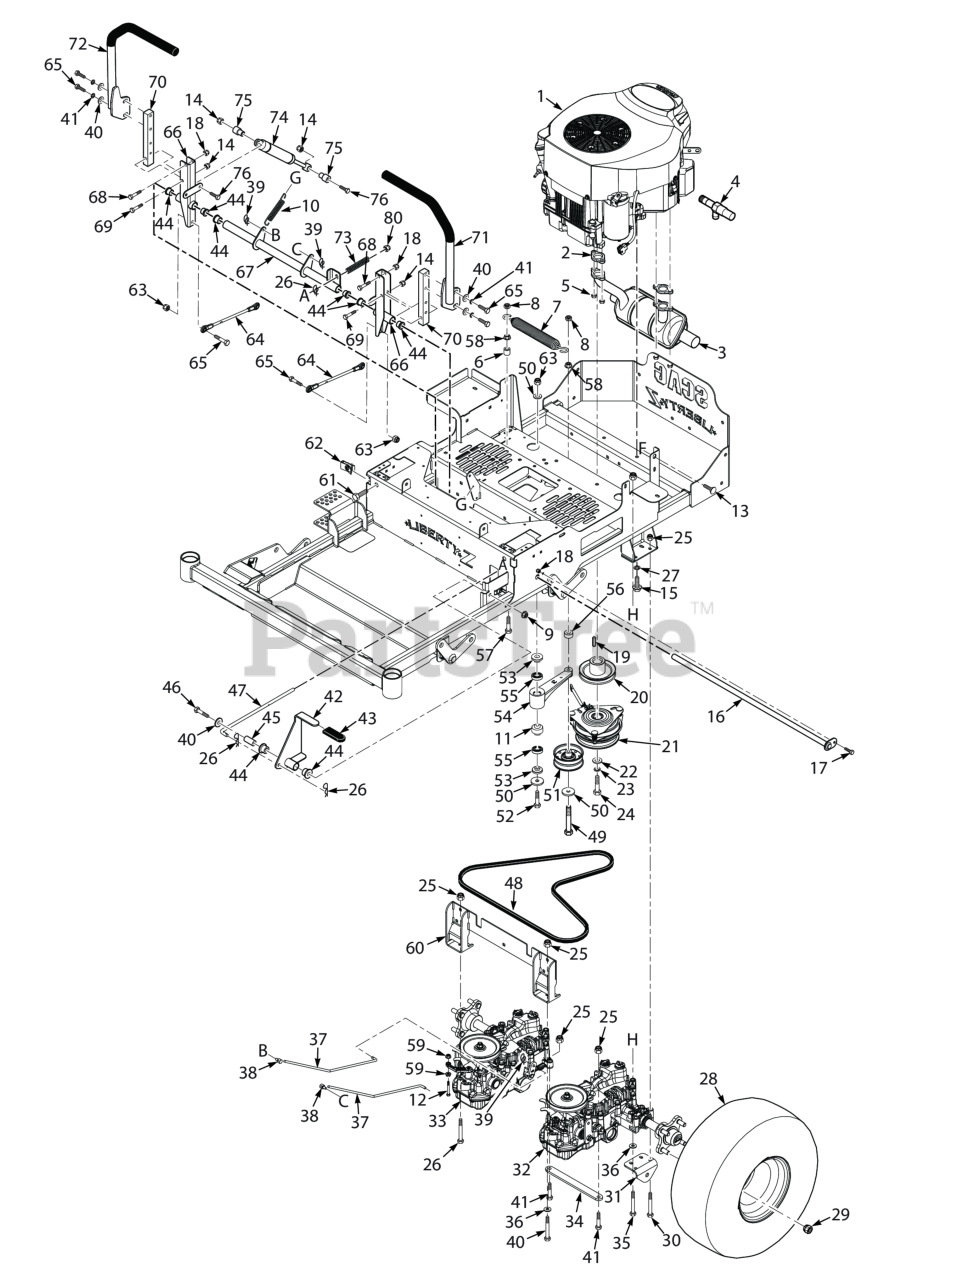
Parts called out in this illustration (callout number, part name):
1	Engine, Kawasaki 21FR
2	Gasket, Exhaust
3	Muffler, Kawasaki FR651V & FR691V
4	Oil Drain, Kawasaki
5	Nut, M8 x 1.25 Hex Special
6	Spacer, Idler Pulley - SFZ52
7	Spring, Transmission Drive
8	Bolt, Hex Head 3/8-16 x 1" Ser. Flg.
9	Nut, Flange Elastic Stop Nut, 3/8-16
10	Spring, Deck Latch
11	Spacer, Bearing
12	Bolt, Hex Head 3/8-16 x 2-1/4" - 61"
13	Serr. Fl. Hex Head CPSCR, 1/4-20 x 3/4"
14	HEX NUT, ELASTIC STOP LOCK, 5/16-18
15	Bolt, Hex Head 3/8-16 x 1-1/4", Kawasaki FX / FT & FT-EFI
16	Shaft Weldment, Control Arm
17	BOLT, HEX HEAD, 1/4-20 X 5/8
18	HEX, NUT, ELASTIC STOP LOCK, 1/4-20
19	Key, 1/4 x 1/4 x 1.25" Pulley Mtg.
20	Pulley, 4-1/2" - 1" Bore
21	Clutch
22	Lockwasher, 7/16� Spring
23	Bolt, Hex Head 7/16-20 x 3¼" w/Patch
24	Bolt, Hex Head 7/16-20 x 2-1/4" w/Patch (Kawasaki)
25	Nut, Flange Head Elastic Stop 5/16-18
26	BOLT, HEX HEAD, 5/16-18 X 2-1/4
27	Lockwasher, 3/8" Spring, Kawasaki FX / FT & FT-EFI / B&S 32BV
28	Wheel Assembly (48, 52)
29	Wheel Nut, 1/2-20 x 13/16
30	Bolt, Hex Head 5/16-18 x 3.00"
31	Bracket, Pusharm
32	Transaxle - Tuff Torq, LH - SZL
33	Transaxle - Tuff Torq, RH - SZL
34	Stiffener, Axle
35	BOLT, HEX HEAD, 5/16-18 X 2-1/4
36	Flatwasher, 5/16-.375 x .875 x .083 (35BV & 37BV-EFI)
37	Rod, Brake - LH
38	Joint, Swivel
39	Pin, Rue Cotter 3/8" Diameter
40	BOLT, HEX HEAD, 5/16-18 X 2-1/4
41	Bolt, Hex Head 3/8-16 x 1-3/4" (Kohler EFI)
42	Brake Lever Assembly
43	Grip, Brake Handle
44	Bearing
45	Pivot, Brake Lever
46	Capscrew, Hex Head 3/8-16 x 2-1/2"
47	Rod, Upper Brake Linkage
48	Belt, Tuff Torq Transmission-SZL
49	Capscrew, Hex Head 3/8-16 x 3-3/4"
50	Flatwasher, 3/8 (.391 x .938 x .105 HD) Grade 8
51	Pulley, 3-1/2" Dia.
52	Bolt, Hex Head 3/8-16 x 3" - 52"
53	Spacer, Controls
54	Trans. Idler Arm Assy. (Includes 24, 79)
55	BEARINGS, BALL, NEUTRAL RETURN
56	Spacer, Idler Pulley - SFZ61
57	Capscrew, Hex Head 3/8-16 x 2.0"
58	NUT, 3/8-16 SERRATED FLANGE HEX HEAD
59	NUT, 1/4-20 SERRATED FLANGE HEX HEAD
60	Mounting Weldment, Axle - Tuff Torq
61	Bolt, Hex Head 3/8-16 x 2-1/2" Soecial Lock
62	U-Nut, 3/8-16
63	HEX NUT, ELASTIC STOP LOCK, 3/8-16
64	Linkage, Pump
65	Bolt, Hex Head 3/8-16 x 1-1/4", Kawasaki FX / FT & FT-EFI
66	Control Arm Assembly
67	Bellcrank Assembly (incl. 44)
68	Bolt, Hex Head, 1/4-20 x 1-1/4"
69	Bolt, Hex Head 5/16-18 x 1-1/2" - Front
70	Bar, Control Lever
71	Handlebar w/Grip
72	Handlebar w/Grip
73	Spring, Brake
74	Damper, Steering
75	Spacer, Pump Dampener
76	Bolt, Hex Head 5/16-18 x 1-1/2" (Right Front Engine Mounting, Briggs and Kohler Only)
